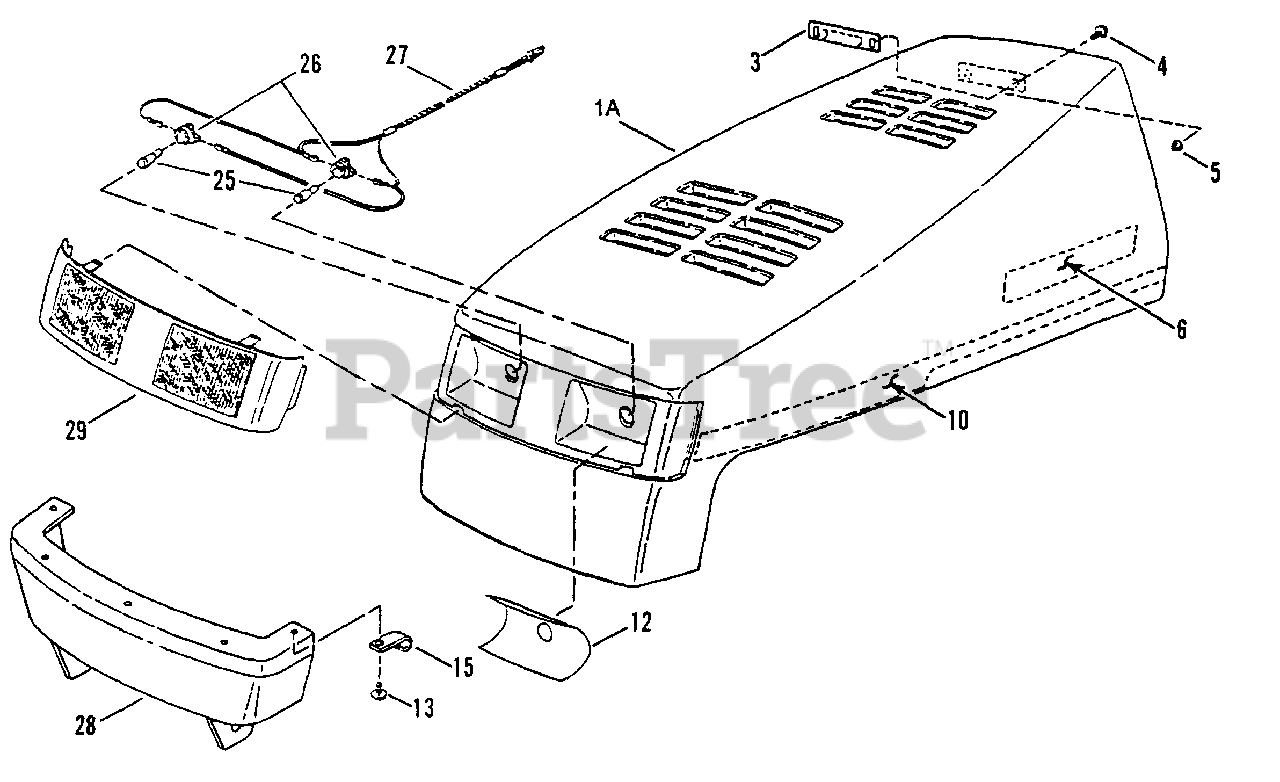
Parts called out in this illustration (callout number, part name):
1A	HOOD
3	LATCH, Spring
4	SCREW, 1/4-20 x 5/8" Truss Head, Torx
4	NUT, #10-24 HEX
5	NUT, 1/4-20 Hex Nyloc
5	SWITCH, Plunger, NC
6	DECAL - SNAPPER, 8" Molded Logo, Silver Letters
6	SCREW, #10-24 X 1/2" ROUND PHILLIPS
10	DECAL, Hood (Right Hand)
10	DECAL, Hood (Left Hand)
10	NUT, 5/16-18 HEX NYLOCK FLANGE
11	WASHER, 5/16" SAE
12	DECAL, Clear Lens (Left Hand)
25	BULB, Headlights
26	SOCKET, Headlight Bulb
27	HARNESS, Headlight Wiring
28	BUMPER, Front Hood Support
29	LENS, Clear
